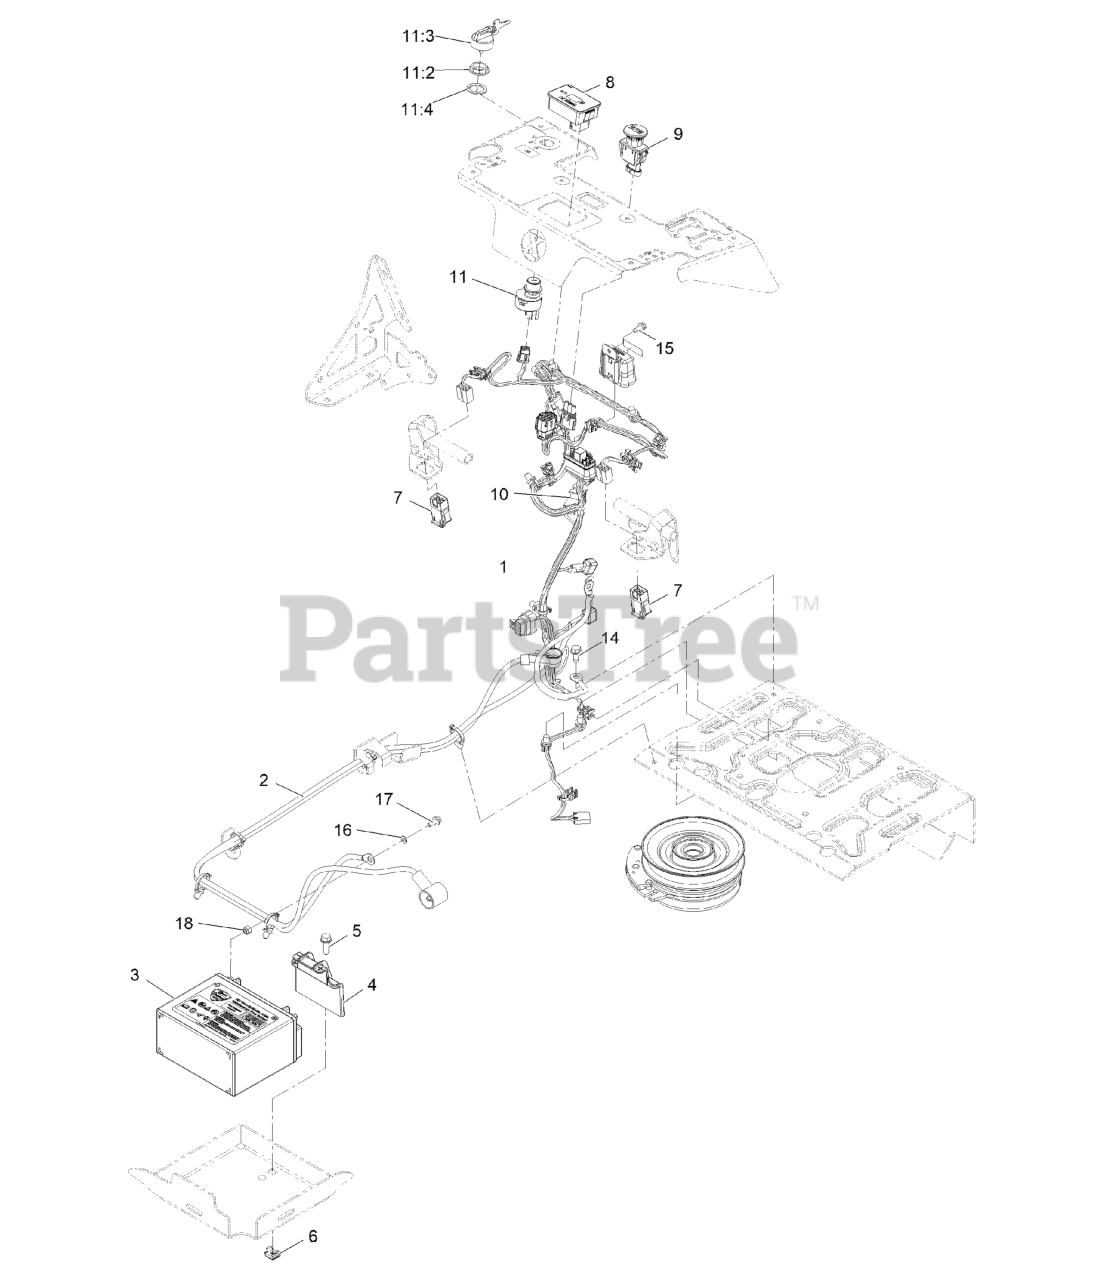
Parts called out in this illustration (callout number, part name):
1	HARNESS-WIRING
2	HARNESS-BATTERY
4	HOLD DOWN, BATTERY
5	SCREW-HHF
6	NUT, SNAP
7	SWITCH-DELTA
8	Module-Hour Meter
9	SWITCH-PTO, SEALED
10	SWITCH-BAIL
11	IGNITION SWITCH ASM
11:2	NUT-MOUNTING
11:3	IGNITION KEY SET
11:4	WASHER-BACKUP
14	SCREW-THD ROLL, HWH
15	SCREW-HWH
16	WASHER-SPRING
17	SCREW-HEAD, FLANGE
18	NUT-LOCK, NI
